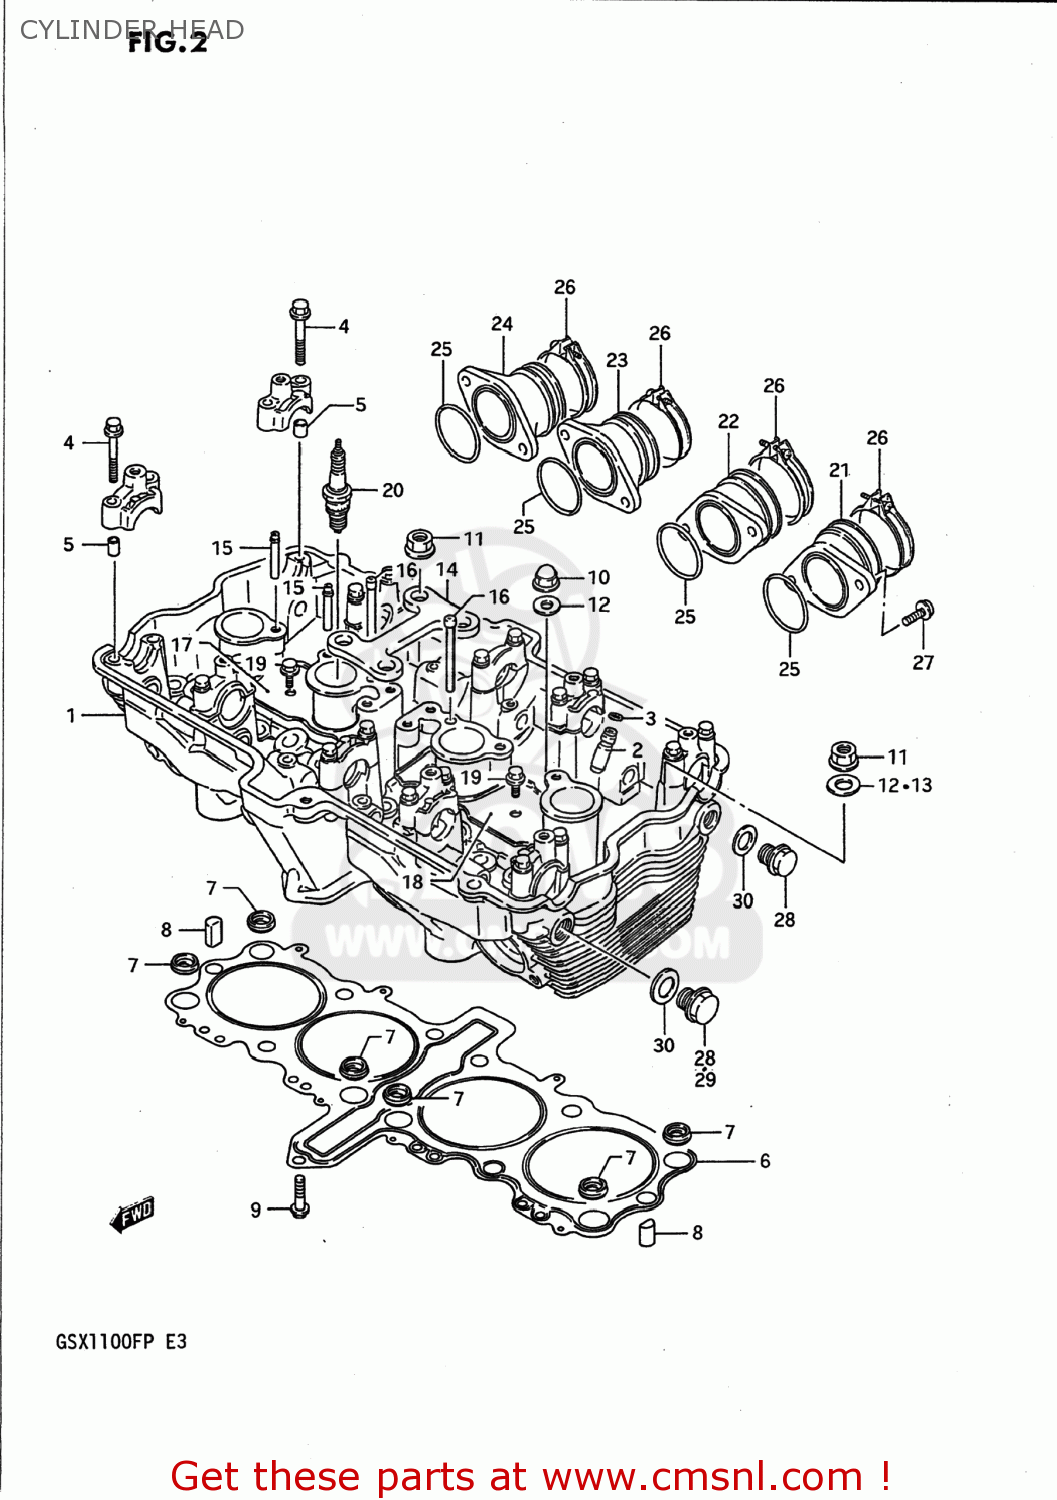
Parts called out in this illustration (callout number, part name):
1	HEAD ASSEMBLY,CYLINDER
2	GUIDE,VALVE
3	RING,SNAP
4	BOLT(6X39)
5	PIN(6.2X8X11)
6	GASKET,CYLINDER HEAD (NAS)
7	O-RING,HEAD GASKET
8	PIN
9	BOLT
10	NUT
11	NUT
12	GASKET(10.2X20X2).3 (NAS)
13	WASHER (10.5X22X2.3)
14	PLATE,HEAD REINF
15	PIPE,OIL NO.1
16	PIPE,OIL NO.3
17	PLATE,OIL PIPE,R
18	PLATE,OIL PIPE,L
19	BOLT
20	PLUG,SPARK(JR9B)
21	PIPE,INTAKE
22	PIPE,INTAKE
23	NET,INTAKE
24	PIPE,INTAKE
25	O RING(D:2.4,ID:39.7)
26	CLAMP
27	SCREW
28	PLUG
29	PLUG
30	GASKET(14X19.2X2) (NAS)
